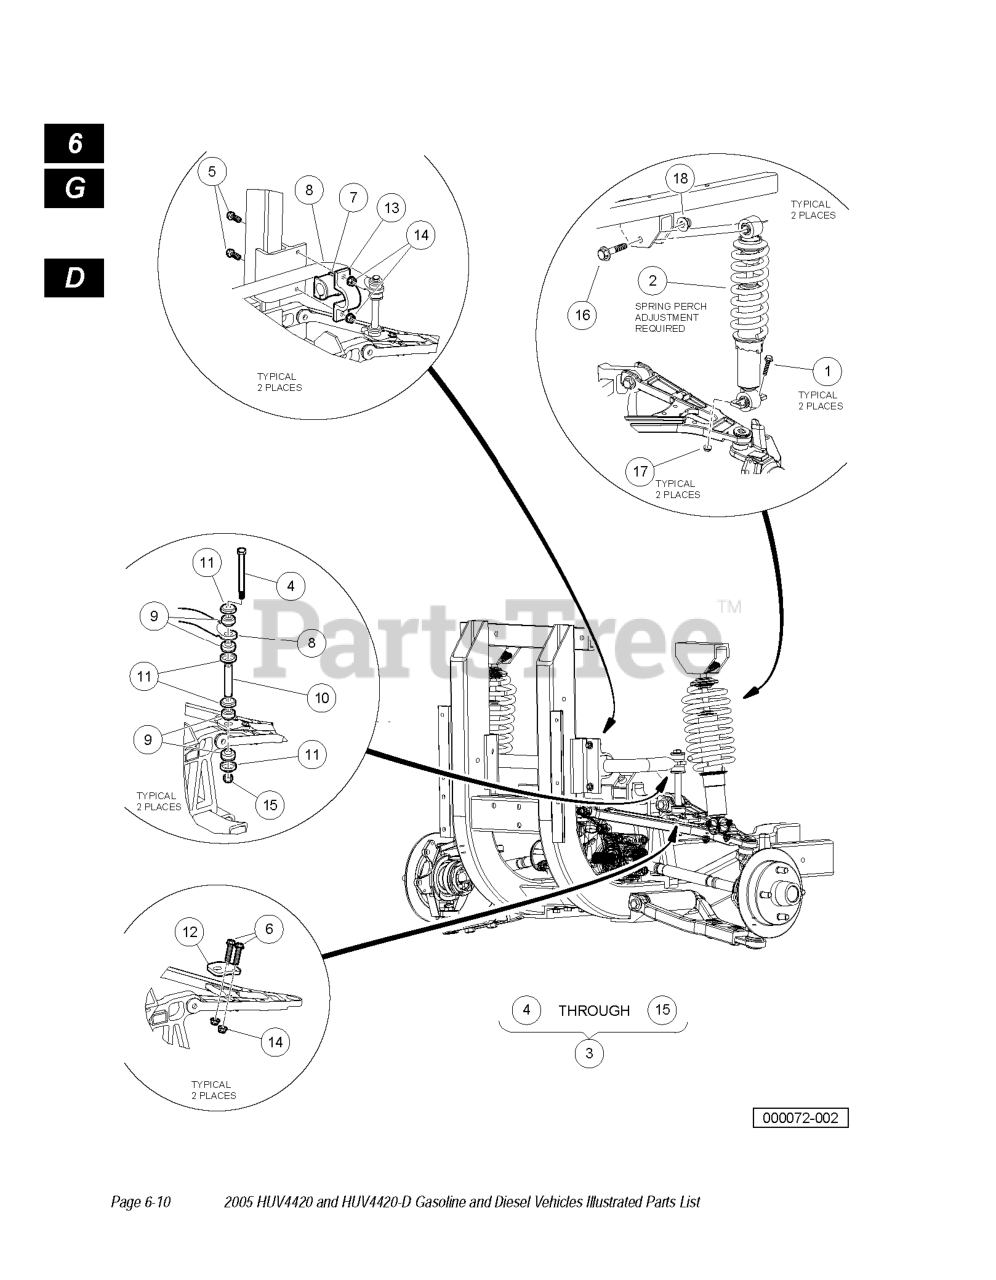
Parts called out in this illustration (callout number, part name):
1	BOLT, FLANGE HD, M8 X 40.0
2	SHOCK, COIL OVER, FRONT HD
3	KIT, ANTI-SWAY BAR
4	SCREW, 3/8-16 X 7.00 HEX CAP
5	BOLT - FLANGED HD, M8 X 30.0
6	BOLT, FLANGE HD, M8 X 40.0
7	BUSHING, ANTI-SWAY BAR, 1-1/8
8	BAR, SWAY, FORMED
9	BUSHING, LINK
10	SLEEVE, LINK
11	WASHER, CUP, BUSHING
12	MOUNT, LINK
13	BRACKET, ANTI-SWAY BAR
14	LOCK NUT, FLG M8 X 1.25 NYLON
15	LOCKNUT, 3/8-16 HEX
16	BOLT, FLG, M12X1.75X70
17	LOCK NUT, FLG M8 X 1.25 NYLON
18	NUT FLG, M12X1.75, NYLON GR 10
